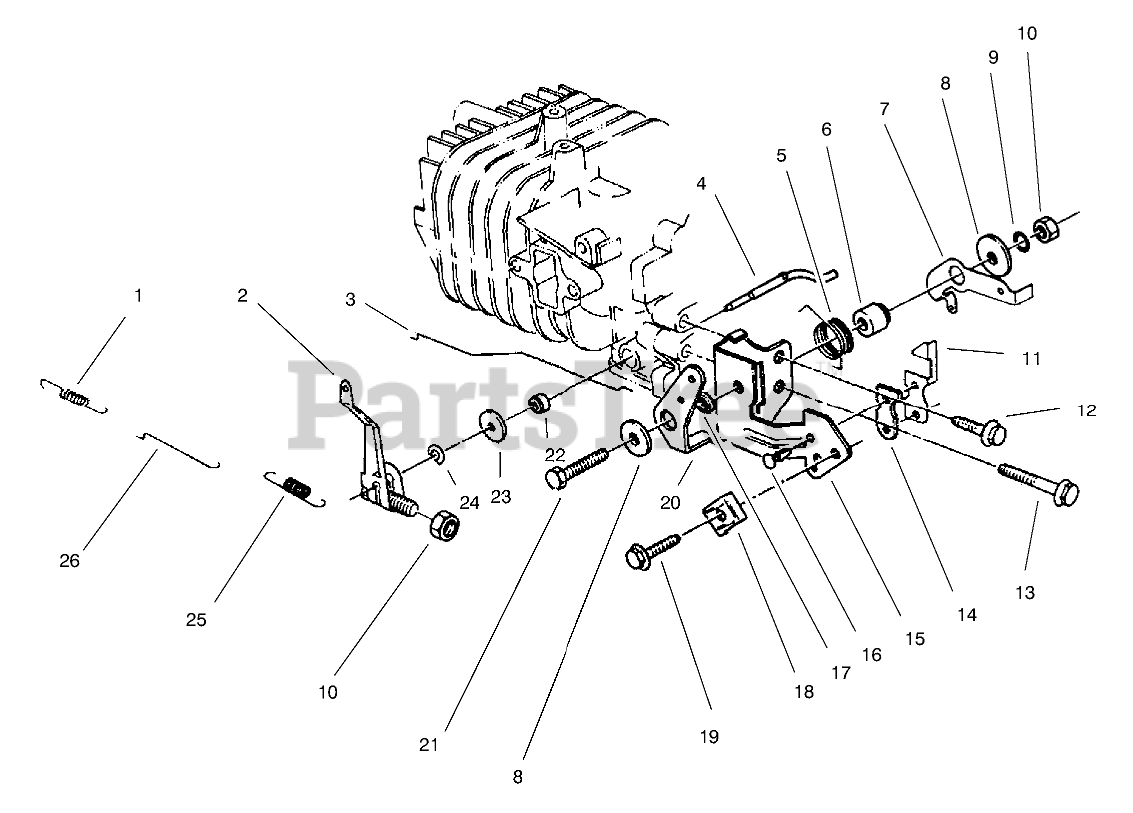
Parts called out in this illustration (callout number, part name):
1	SPRING
2	ARM-GOVERNOR
3	ROD-CHOKE
4	SHAFT
5	SPRING-CHOKE LEVER
6	SPACER
7	LEVER-SPRING, GOVERNOR
8	WASHER
9	LOCKWASHER
11	TERMINAL-KILL SWITCH
14	INSULATOR-KILL SWITCH
15	BRACKET-THROTTLE, CONTROL
16	RIVET
17	SPACER-CHOKE LEVER
18	CLAMP
20	LEVER-CONTROL, CHOKE
22	SEAL-OIL
23	WASHER
24	E-RING
25	SPRING-GOVERNOR
26	ROD-CARBURETOR
